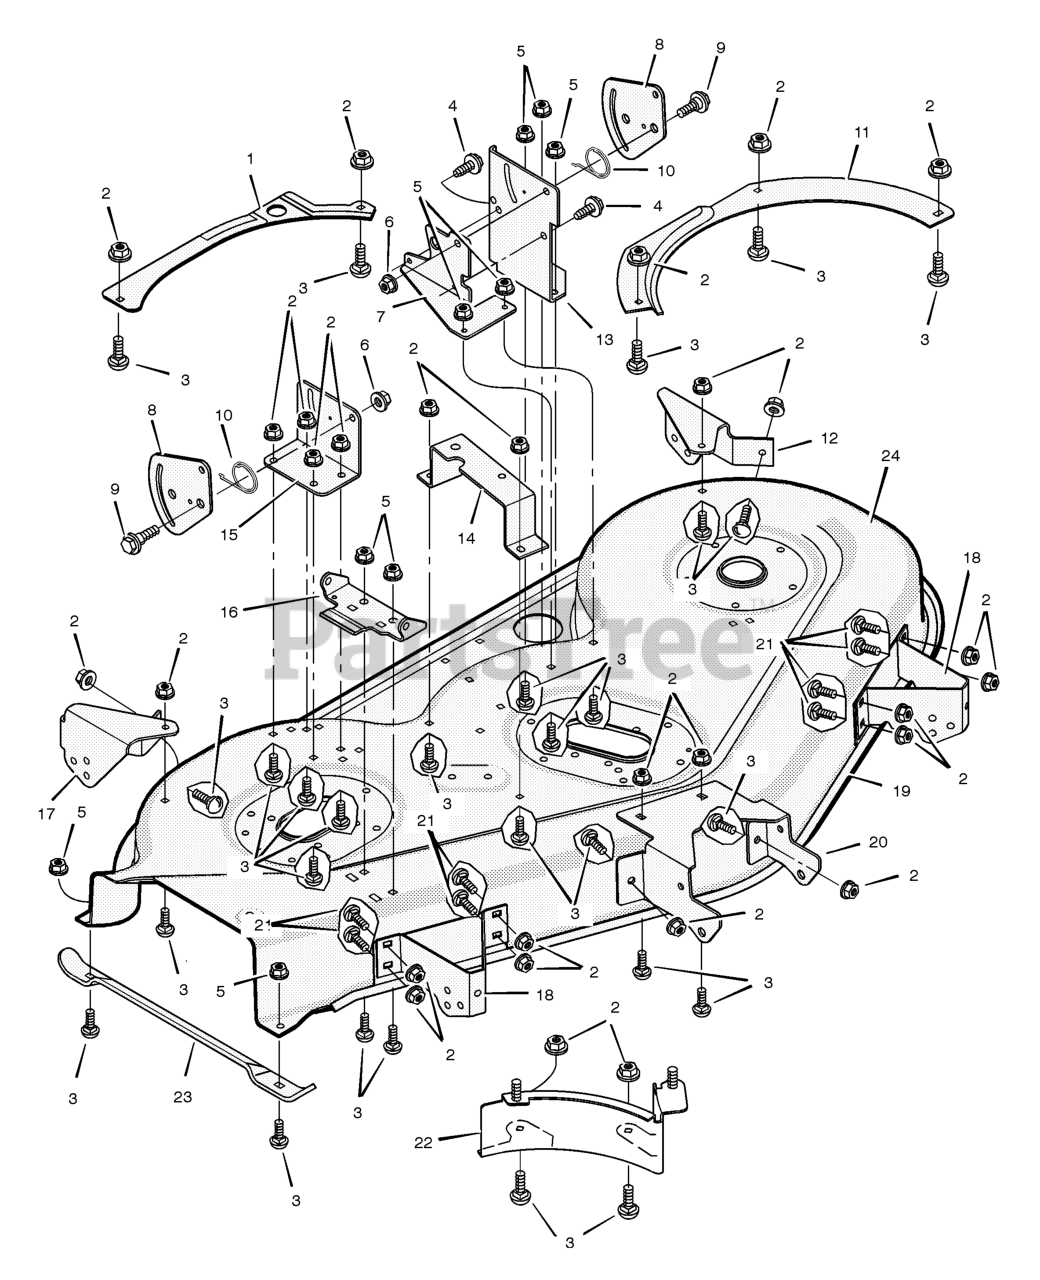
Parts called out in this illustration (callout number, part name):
1	Baffle, Right Bottom
2	Locknut, Flange
3	Bolt, Carriage
5	Locknut
6	Locknut
7	Brace, Hi Lifter
8	Plate, Suspension
9	Bolt, Shoulder
10	Spring, Torsion
11	Baffle, Left Bottom
12	Bracket, Rear Gage Wheel
13	Bracket, Left Lifter
14	Bracket, Bellcrank
15	Bracket, Right Lifter
16	Bracket, Hinge
17	Bracket, Rear Gage Wheel
18	Bracket, Front Gage Wheel
19	Assembly, Reinforcement
20	Bracket, Front Deck
21	Bolt, Carriage
22	Assembly, Baffle
23	Bracket, Chute Support
